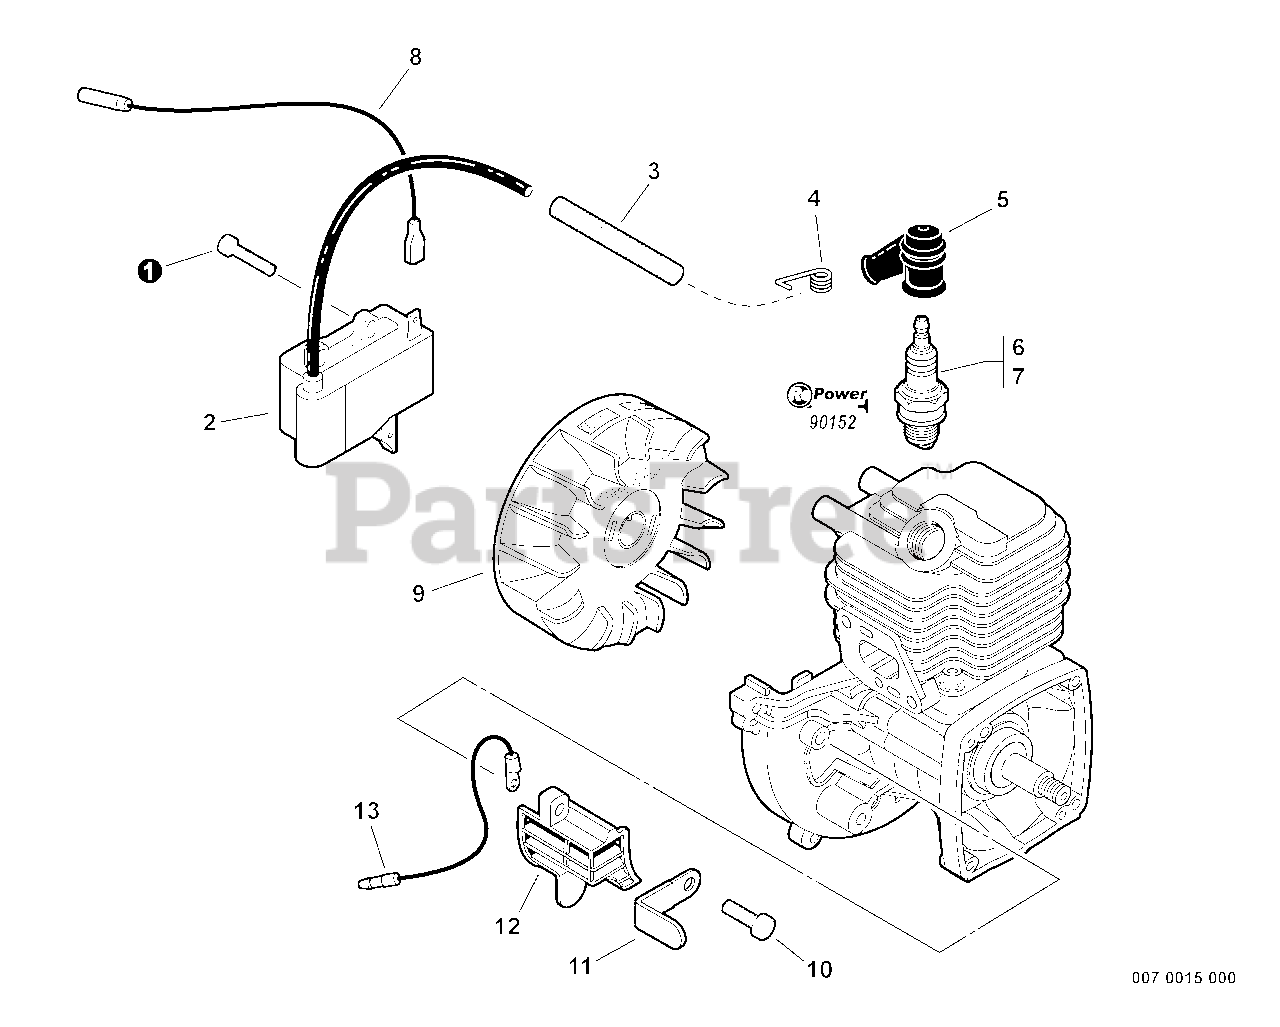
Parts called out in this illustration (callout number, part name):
1	SCREW - 4X20
2	COIL, IGNITION
3	TUBE, INSULATOR
4	TERMINAL, SPARK PLUG CAP
5	CAP, SPARK PLUG
6	SPARK PLUG -- BPM-8Y
7	SPARK PLUG -- BPMR-8Y
8	LEAD - IGNITION
9	FLYWHEEL
10	SCREW - 5X16
12	GUARD, DEBRIS
13	LEAD - GROUND
14	RePower TUNE-UP KIT
